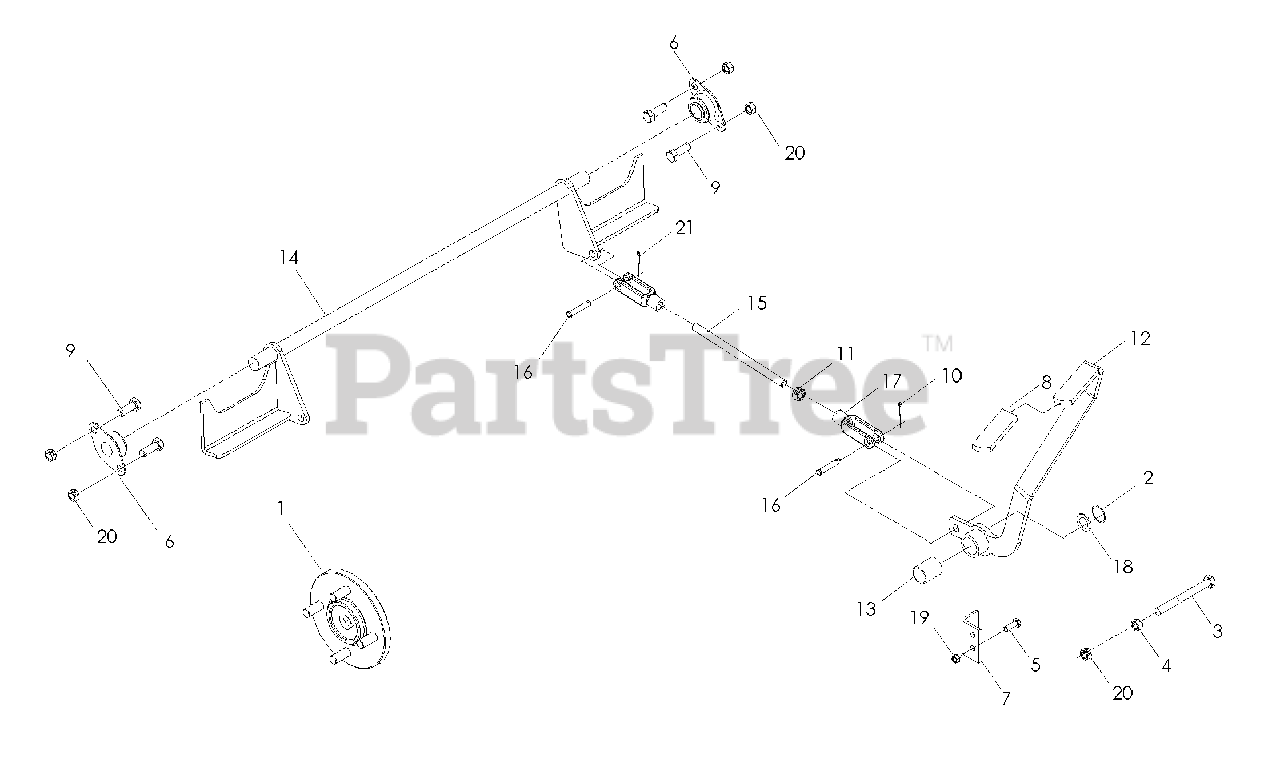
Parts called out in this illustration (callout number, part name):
2	RING, RETAINING EXT 7/8
3	HCS 3/8-16 x 2 1/2
4	NUT 3/8-16 WHIZLK
5	HCS 1/4-20 x 3/4
6	BEARING, FLANGED
8	GRIP, PARK BRAKE
9	HCS 3/8-16 x 1
10	PIN, COTTER 1/8 x 3/4
11	NUT 3/8-24 HEX NYLOC GR2
12	BRAKE LEVER
14	BRAKE CROSS SHAFT
16	PIN, CLEVIS 3/8 x 1 1/8
17	YOKE 3/8-24
19	NUT 1/4-20 HEX NYLOC
20	NUT 3/8-16 HEX NYLOC
